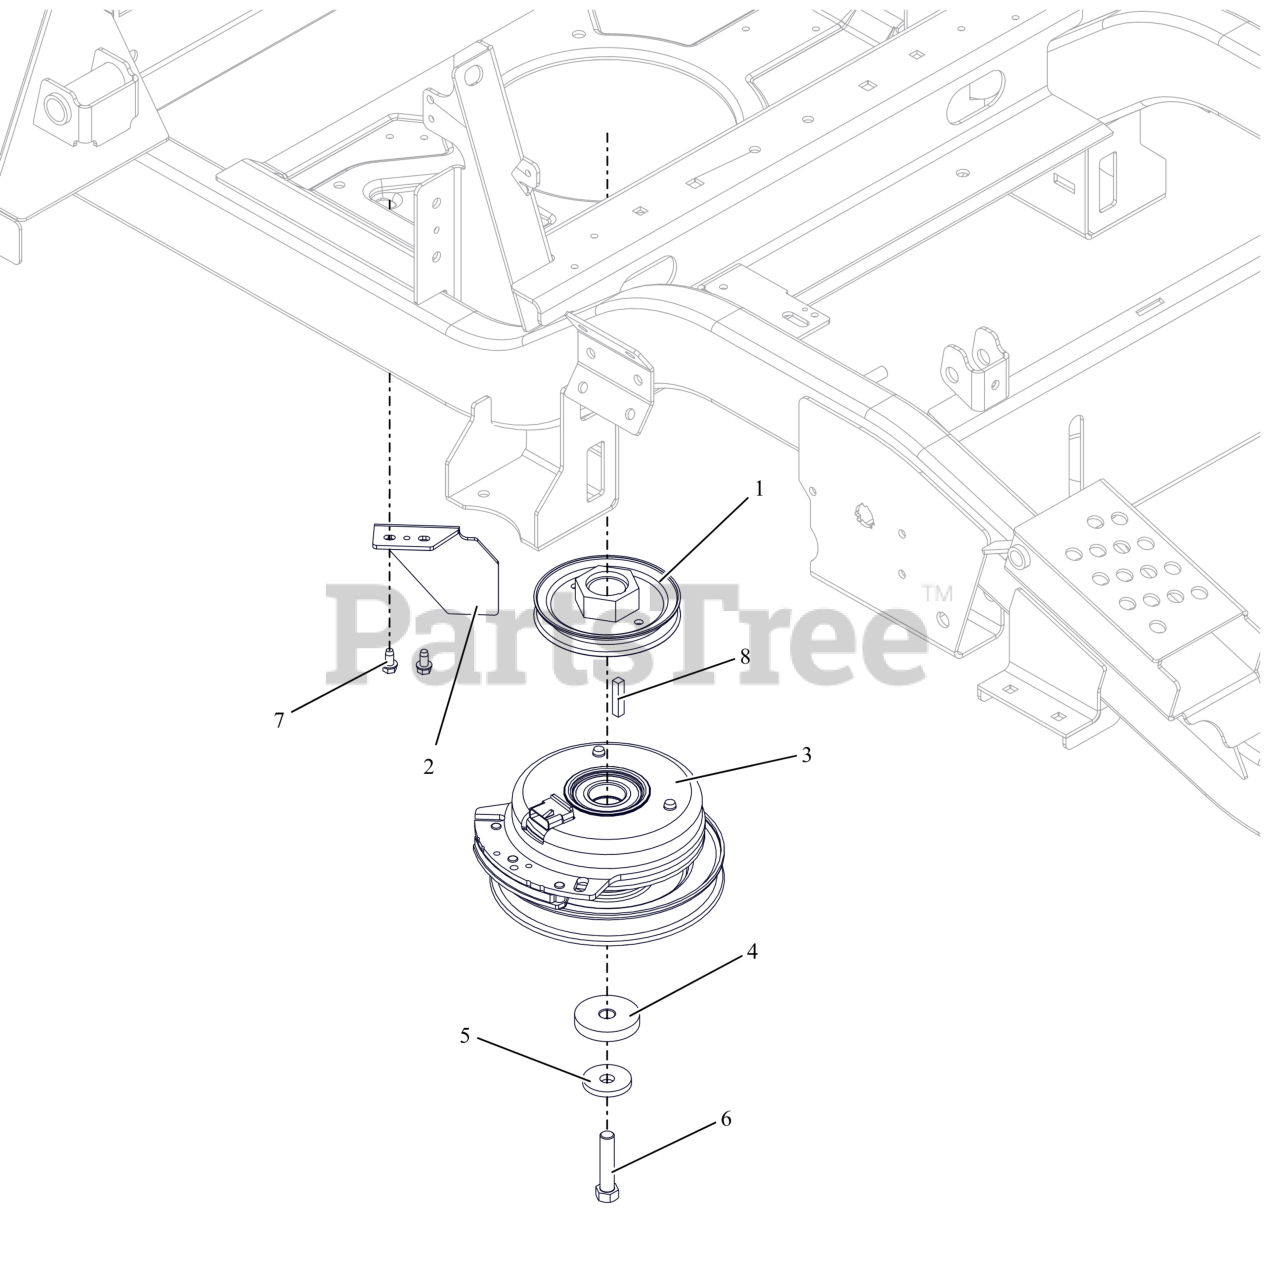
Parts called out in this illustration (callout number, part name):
1	WLDMT,PULLEY-4.50ODX1.127
2	BRKT- CLUTCH STOP HD
3	CLUTCH- WARNER 1.125 PT-ZX
4	SPACER, .474/.459X2.00X.350
5	WASHER, 7/16" SPRING DISK
6	BLT, HEX 0.4375-20X2 G8 ZCC NT
7	SCR-TAP .25-20X.50 HWH ZCC
8	KEY-SQ .25 X 1.25 X .25 SAE
